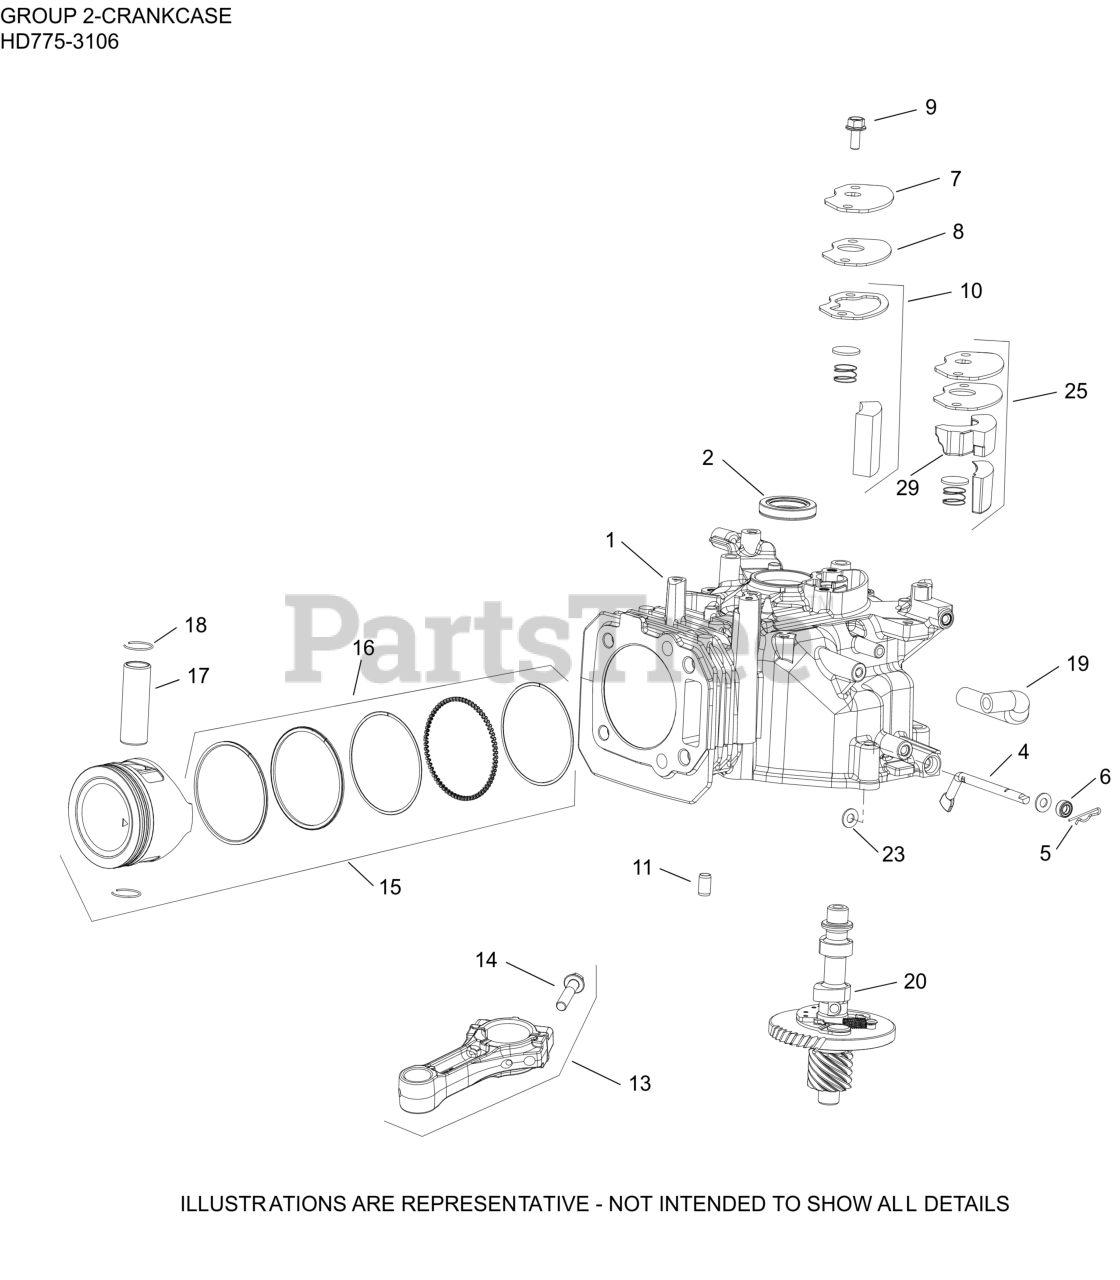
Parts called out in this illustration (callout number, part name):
1	CRANKCASE
2	SEAL, CCASE/FLYWHEEL
4	SHAFT, GOVERNOR CROSS
5	CLIP, GOVERNOR SHAFT
6	SEAL, OIL
7	COVER, BREATHER
8	GASKET, BREATHER COVER
9	SCREW, HEX FLANGE (M6)-USE 25 086 433-S
10	KIT, BREATHER FILTER
11	PIN, DOWEL (8mm)
13	CONNECTING ROD
14	SCREW, HEX FLANGE (M7)
15	KIT, PISTON
17	PIN, PISTON
18	RETAINER, PISTON PIN
19	HOSE, BREATHER
20	CAMSHAFT ASSEMBLY
23	WASHER, FLAT (DIA 13mm O.D.)
25	KIT, BREATHER FILTER
29	FILTER, BREATHER MEDIA-USE 14 050 31-S
